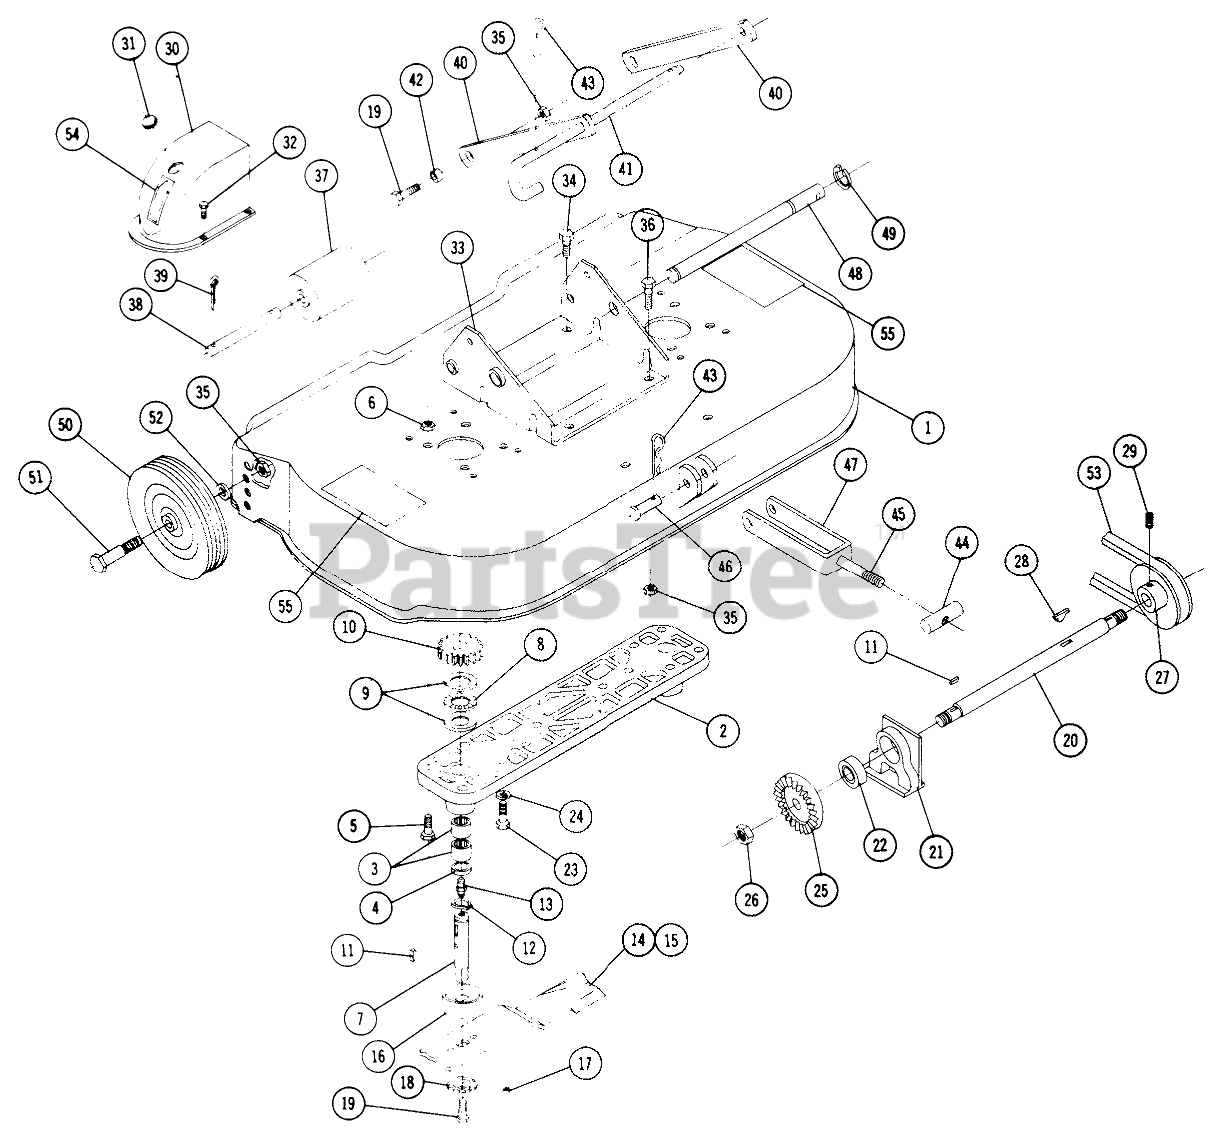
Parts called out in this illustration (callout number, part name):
1	Ass-y. Deck
5	Bolt, 5/16-18 X 7/8
6	Nut-Nylok
9	WASHER-THRUST
17	SPIROL ROLL PIN
19	Bolt 3/8-16 x 7/8
21	BEARING SUPPORT
23	Bolt 3/8-16 x 1
24	Lockwasher
29	Set Screw
31	PLUG BUTTON
32	SCREW
33	Hanger
34	Bolt 3/8-16 x 3/4
35	3/8-16 E.S.
36	Bolt 3/8-16 x 1
39	Cotter Pin
43	Hairpin
45	Bolt Square Head 1/2-13 x 2 3/4
46	Clevis Pin
48	Shaft-Belt Tightener
49	E-RING
51	BOLT-SHOULDER
52	Washer
53	V BELT
54	Decal
